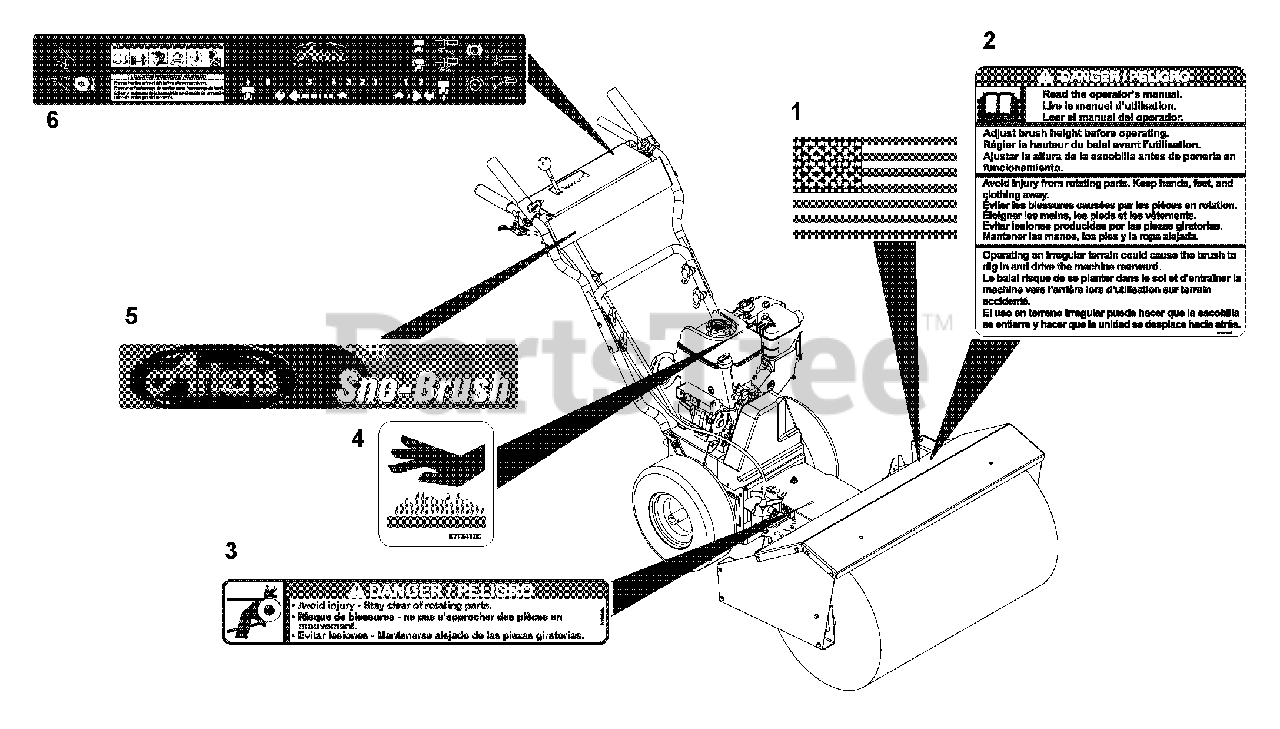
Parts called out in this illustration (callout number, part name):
1	DECAL, AMERICAN FLAG
2	DECAL, DANGER - POWER BRUSH
3	DECAL- DANGER
4	DECAL, HOT SURFACE
5	DECAL,DASH SNO-BRUSH
6	DECAL,CONTROL SNO-BRUSH
